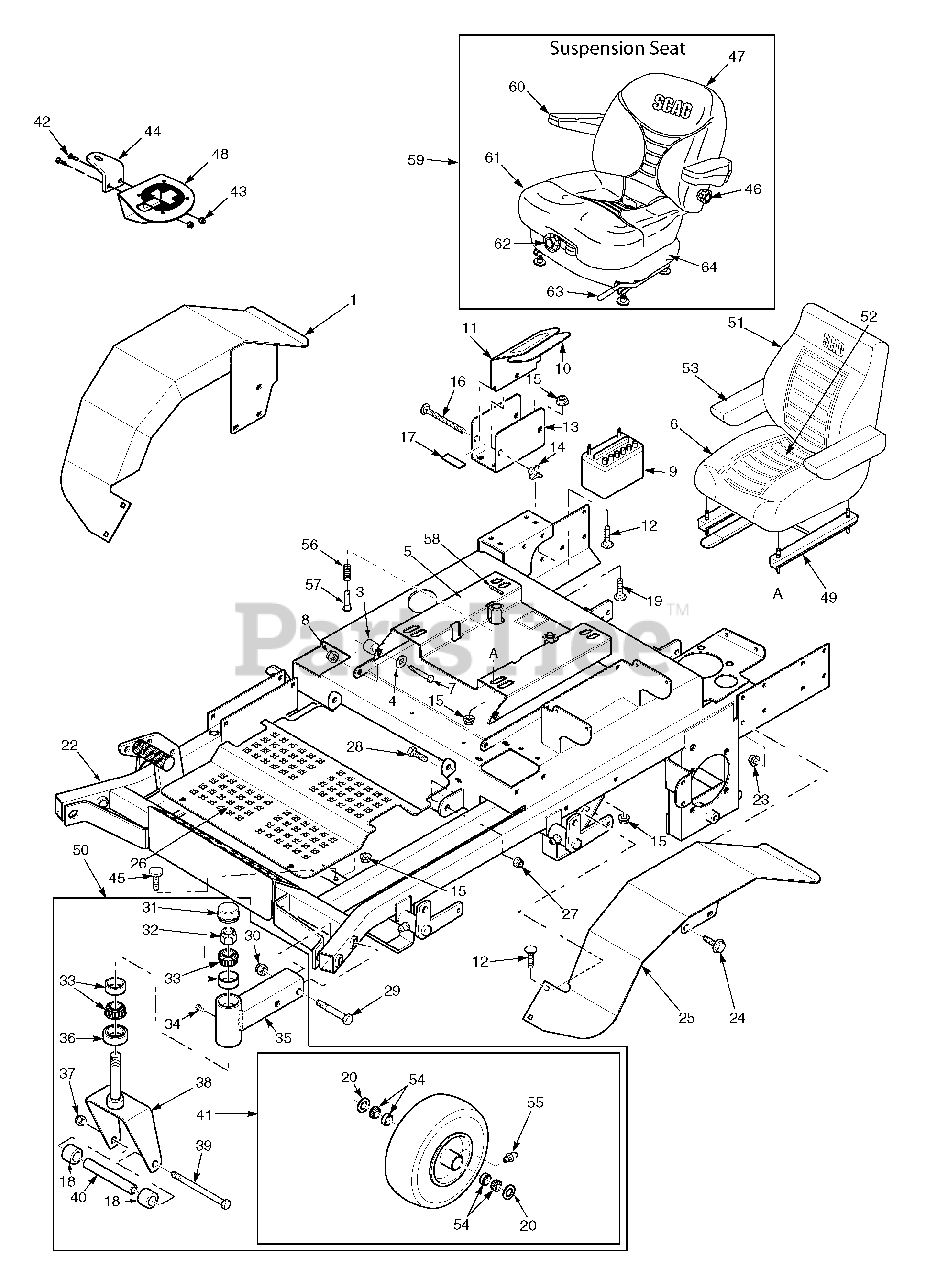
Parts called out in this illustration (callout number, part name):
1	Fender Weldment, RH
2	Bolt, Hex Head, 5/16-18 x 1, Zinc
3	Spacer
4	Flatwasher, 3/8-.391 x .938 x .105
5	Seat Plate Weldment
6	Seat Assembly w/armrest and seat belt
7	Bolt, Hex Head 3/8-16 x 2.0"
8	Nut, Elastic Stop 3/8-16
9	Battery
10	Pad, Battery Cover
11	Cover, Battery
12	Bolt, Carriage 5/16-18 x 3/4"
13	Plate, Battery Box
14	Wing Nut, 1/4-20 x 3/4"
15	Nut, Hex Serrated Flange 5/16-18
16	Bolt, Carriage 1/4-20 x 6"
17	Rubber Pad
18	Spacer, Caster Wheel
19	Bolt, Carriage 5/16-18 x 1"
21	Lock Nut, 3/8-16, Elast. Stop
22	Main Frame
23	Nut, Hex Serrated Flange 3/8-16
24	Screw, Hex Serrated Flange 3/8-16 x 1"
25	Fender Weldment, LH
26	Foot Plate
27	Nut, Hex Elastic Stop 3/8-16
28	Bolt, Hex Head 3/8-16 x 1"
29	Bolt, Hex Head 5/8-11 x 4"
30	Nut, Hex Elastic Stop 5/8-11
31	Cap, Grease
32	Nut, Hex Elastic Stop 1.0-14
33	Bearing W/Race
34	Plug, 1/4-28 THD Form
35	Extention Weldment, Caster 52A
36	Seal, 2.00 OD. x 1.625 Bore
37	Nut, Hex Elastic Stop 1/2-13
38	Yoke Weldment, Caster (52A)
39	Bolt, Hex Head 1/2-13 x 7-1/2" (52A)
40	Sleeve, Caster Wheel (52A)
41	Wheel Assy, 52A
42	Bolt, Hex Head 1/4-20 x 3/4"
43	Bolt, Hex Head 1/4-20 x 3/4"
44	Mounting Bracket, STT Cup Holder
45	Lumbar Kit
46	Cable, Seat Stop
47	Back Cushion Kit
48	Cup Holder Assembly
49	Seat Adjustment, Track Set
50	Caster Wheel Assy 52V
51	Back Cushion Cover
52	Seat Cushion Cover
53	Arm Rest, Right Hand
54	Bearing w/ Race
55	Grease Fitting
56	Spring, Seat
57	Pin Retainer, Spring
58	Roll Pin, Spring 5/32 x 3/4"
59	Suspension Seat Assembly w/seat belt
60	Armrest Only
61	Seat Cushion Kit
62	Weight Adjustment Kit
63	Seat Adjustment, Track Set
64	Shock Absorber Kit
